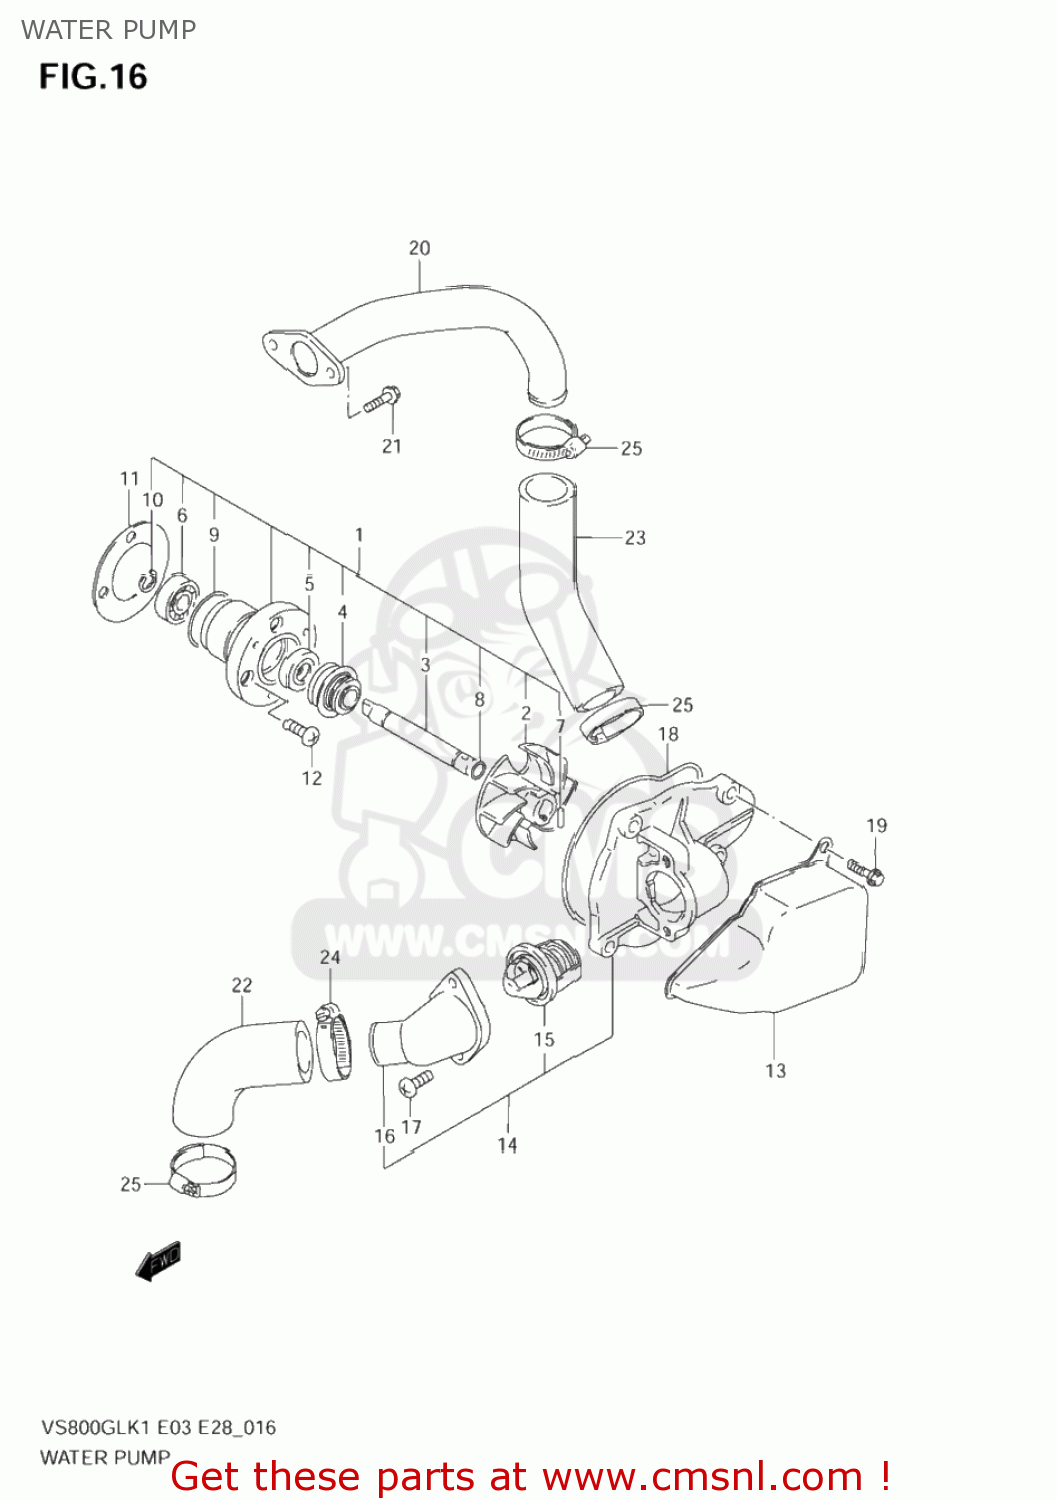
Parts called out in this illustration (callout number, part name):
1	PUMP ASSEMBLY,WATER
2	IMPELLER
3	SHAFT
4	SEAL,MECHANICAL
5	SEAL,OIL(10X21X5)
6	BEARING(10X22X6)
7	PIN
8	O RING
9	O RING
10	E RING
11	GASKET,WATER PUMP (NAS)
12	SCREW
13	COVER,WATER PUMP
14	CASE ASSY,WATER PUMP
15	THERMOSTAT,WATER
16	CONNECTOR
17	SCREW
18	O RING,WATER PUMP CAP
19	BOLT
20	PIPE,CYLINDER INLET
21	BOLT
22	HOSE,WATER PUMP IN
23	HOSE,WATER PUMP OUTLET
24	CLAMP
25	CLAMP
